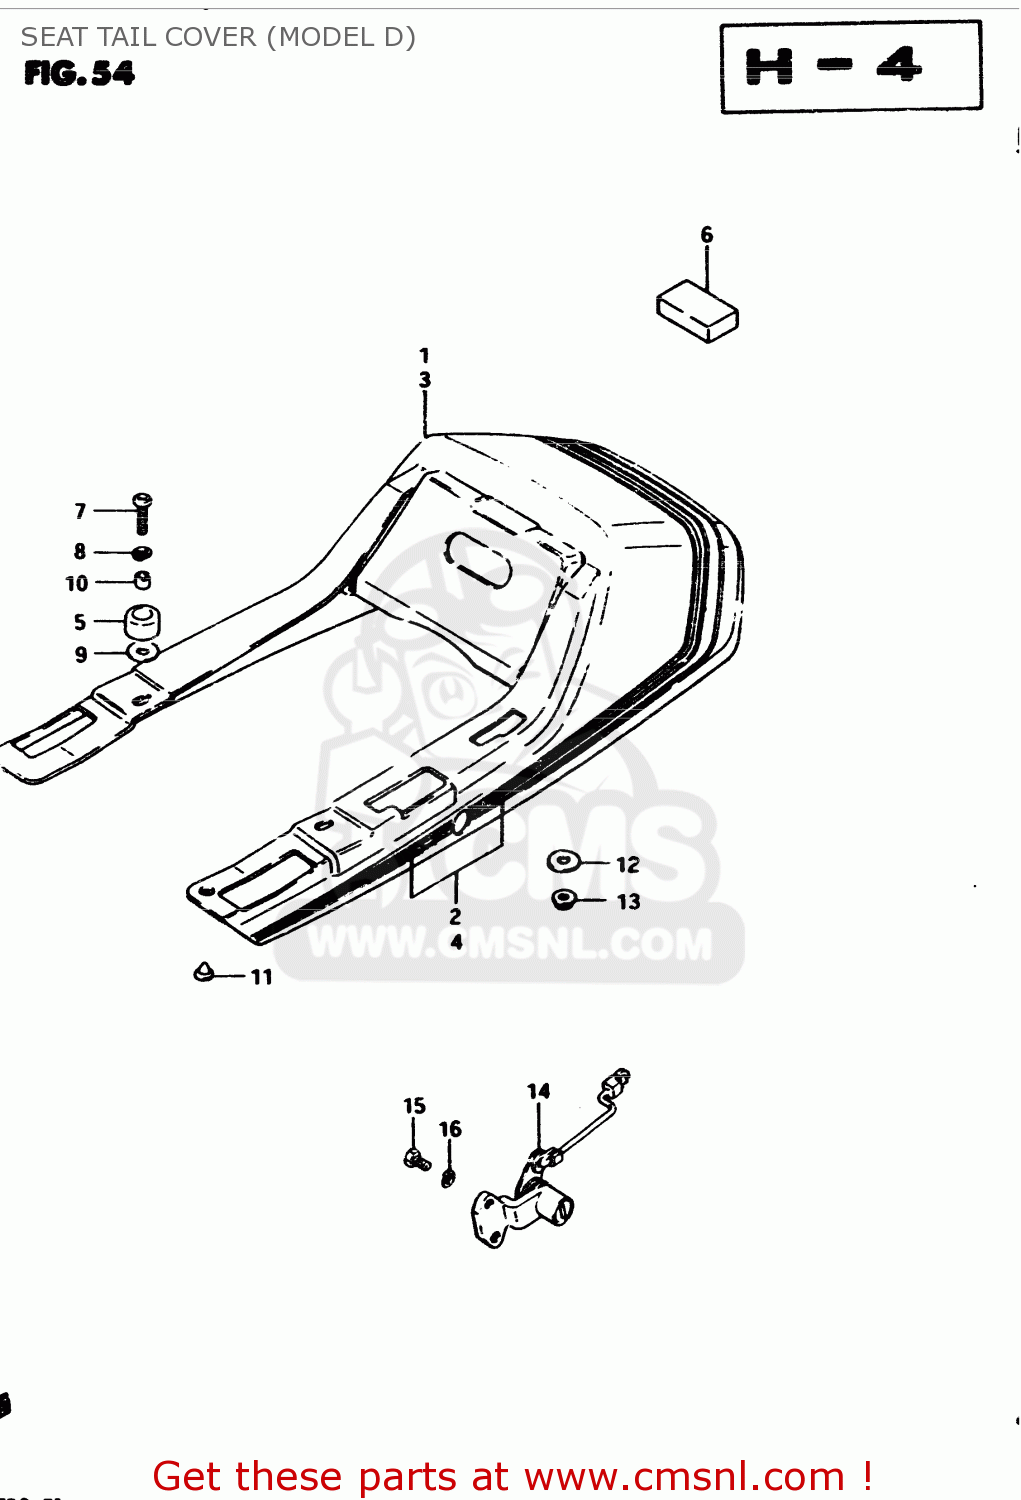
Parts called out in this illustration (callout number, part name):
1	COVER,SEAT TAI
2	TAPE SET, SEAT TAIL COVER
3	COVER,SEAT TAI
4	TAPE SET, SEAT TAIL COVER
5	CUSHION,COVER
6	CUSHION
7	SCREW 6X30
8	LOCK WASHER
9	WASHER (6.5X24X1.6)
10	SPACER
11	CUSHION
12	WASHER
13	NUT 6MM
14	LOCK ASSEMBLY,SEAT
15	BOLT 5X10
16	LOCK WASHER
